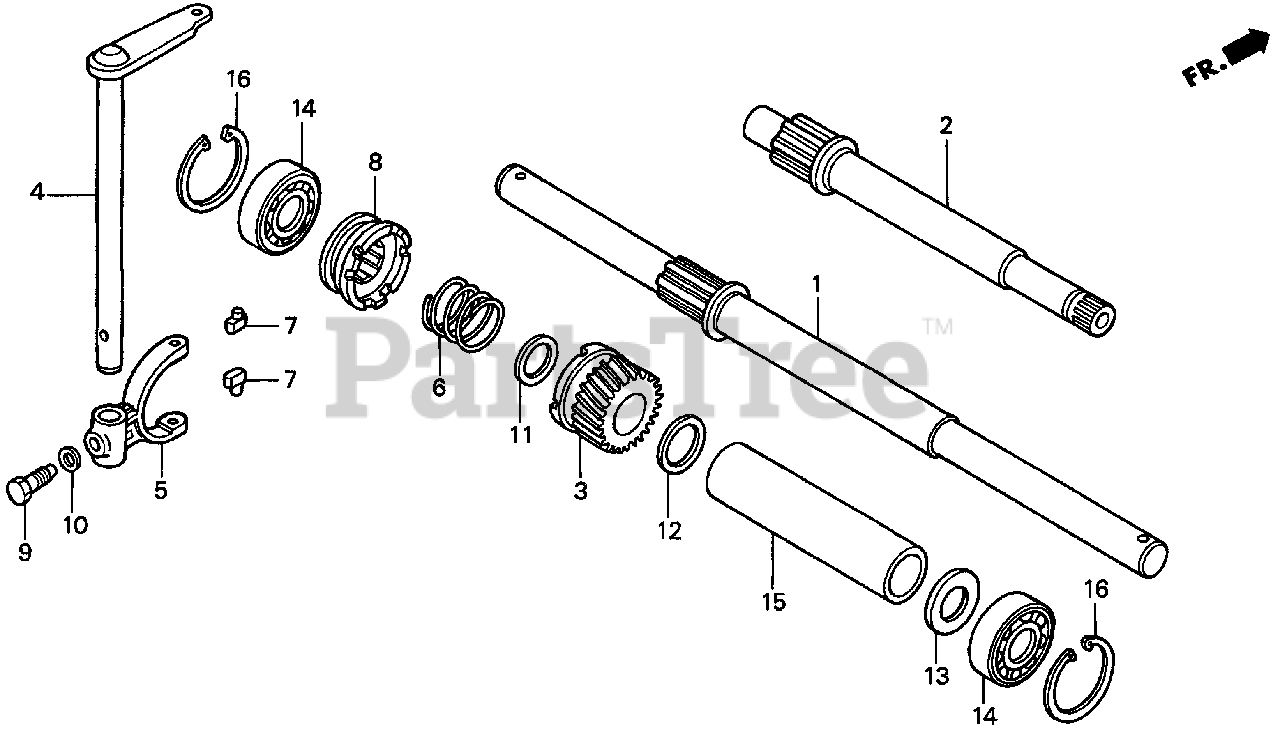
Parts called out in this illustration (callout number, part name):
1	SHAFT, WHEEL
3	GEAR, FINAL
4	SHAFT, GEARSHIFT
5	FORK, GEARSHIFT
6	SPRING, CLUTCH RETURN
7	PIN, GEARSHIFT FORK
8	SHIFTER, MAIN CLUTCH
9	BOLT, SPECIAL (8X24)
10	WASHER, CONICAL SPRING (8MM)
11	WASHER, THRUST (25.2X30)
12	WASHER, THRUST (25MM)
13	WASHER, THRUST (20MM)
14	BEARING, RADIAL BALL (6204)
15	COLLAR, WHEEL SHAFT
16	CIRCLIP (INNER) (47MM)
